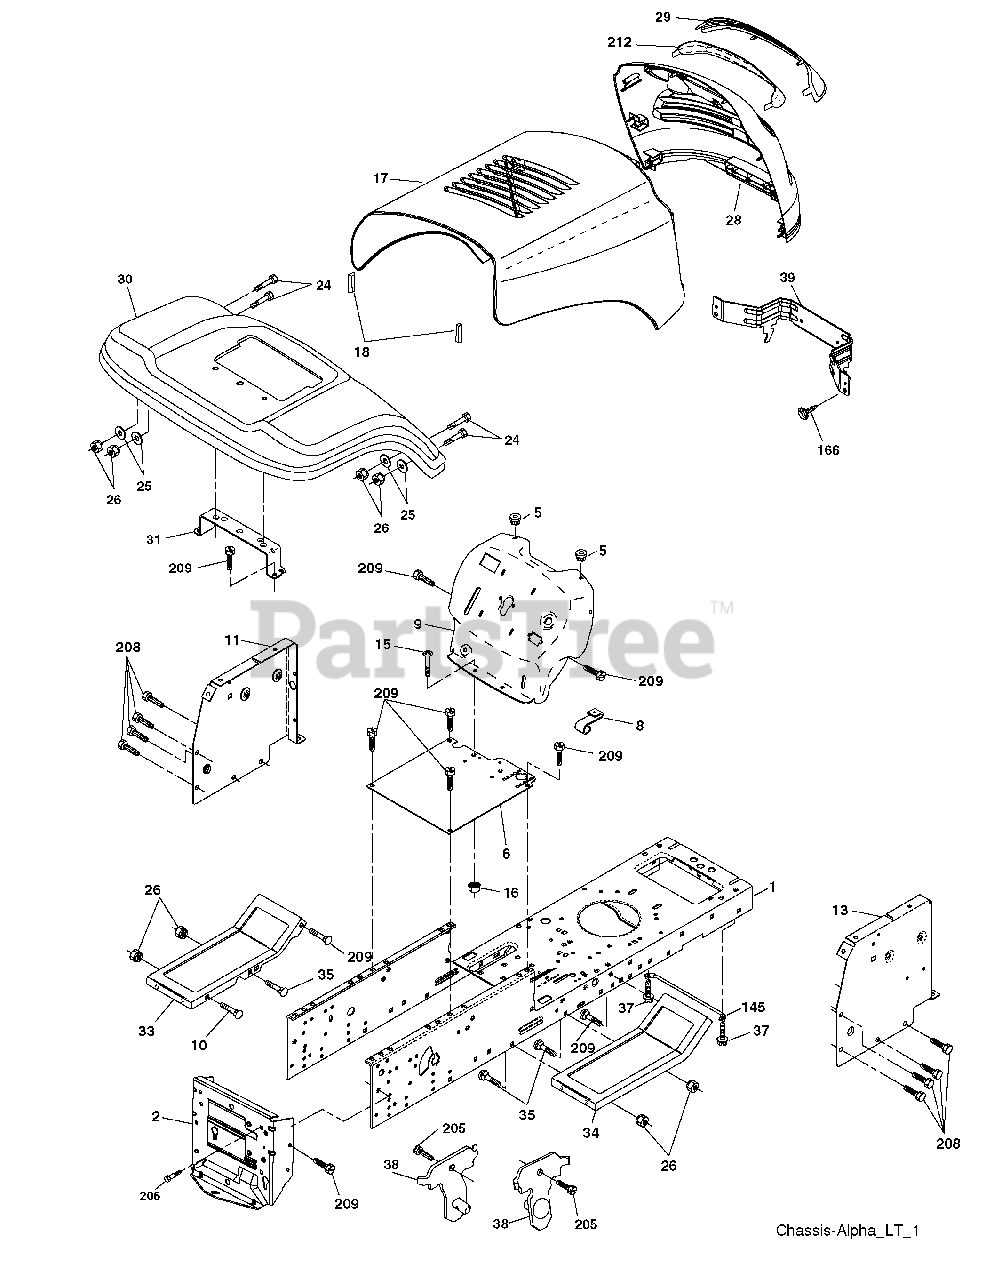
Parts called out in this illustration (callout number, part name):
1	Chassis
2	Drawbar, Stretch
5	Bumper, Hood/Dash
6	Saddle
8	Clip Retainer Slide-On
9	Dash
10	Bolt, Carriage 3/8-16 x 1
11	Panel Dash LH
13	Panel Slkscr Dash RH
15	Screw Mach TRHD 5/16-18 unc x 3/4
16	Nut Keps 5/16-18 unc
17	Hood
18	Bumper Hood
24	Bolt Fin Hex 3/8-16 unc x 1 Gr. 5
25	Washer 13/32 x 13/16 x 12 Ga.
26	Nut Lock Hex w/Ins 3/8-16 unc
28	Grille/Lens Asm.
29	Lens Grille Bar
30	Fender
31	Bracket Fender Repl 109873X
33	Footrest Pnt LH
34	Footrest Pnt RH
35	Bolt Rdhd Sht Sqnk 3/8-16 x 3/4
37	Screw Thdrol 5/16-18 x 1/2 TYT
38	Bracket Asm. Pivot Mower
39	Bracket Pivot
145	Rod Pivot Chassis/Hood
205	Screw Thdrol 3/8-16 x 1/2
206	Bolt Shoulder 5/16-18
208	Screw Thdrol 3/8-16 x 1/2
209	Screw Hex Wsh Thdrol 3/8-16
212	Insert Lens Reflect
278	Screw 10 x 3/4 Single Lead Hex
278	Plug Button Blk 359 Dia Choke
278	Plug Dome Plastic
